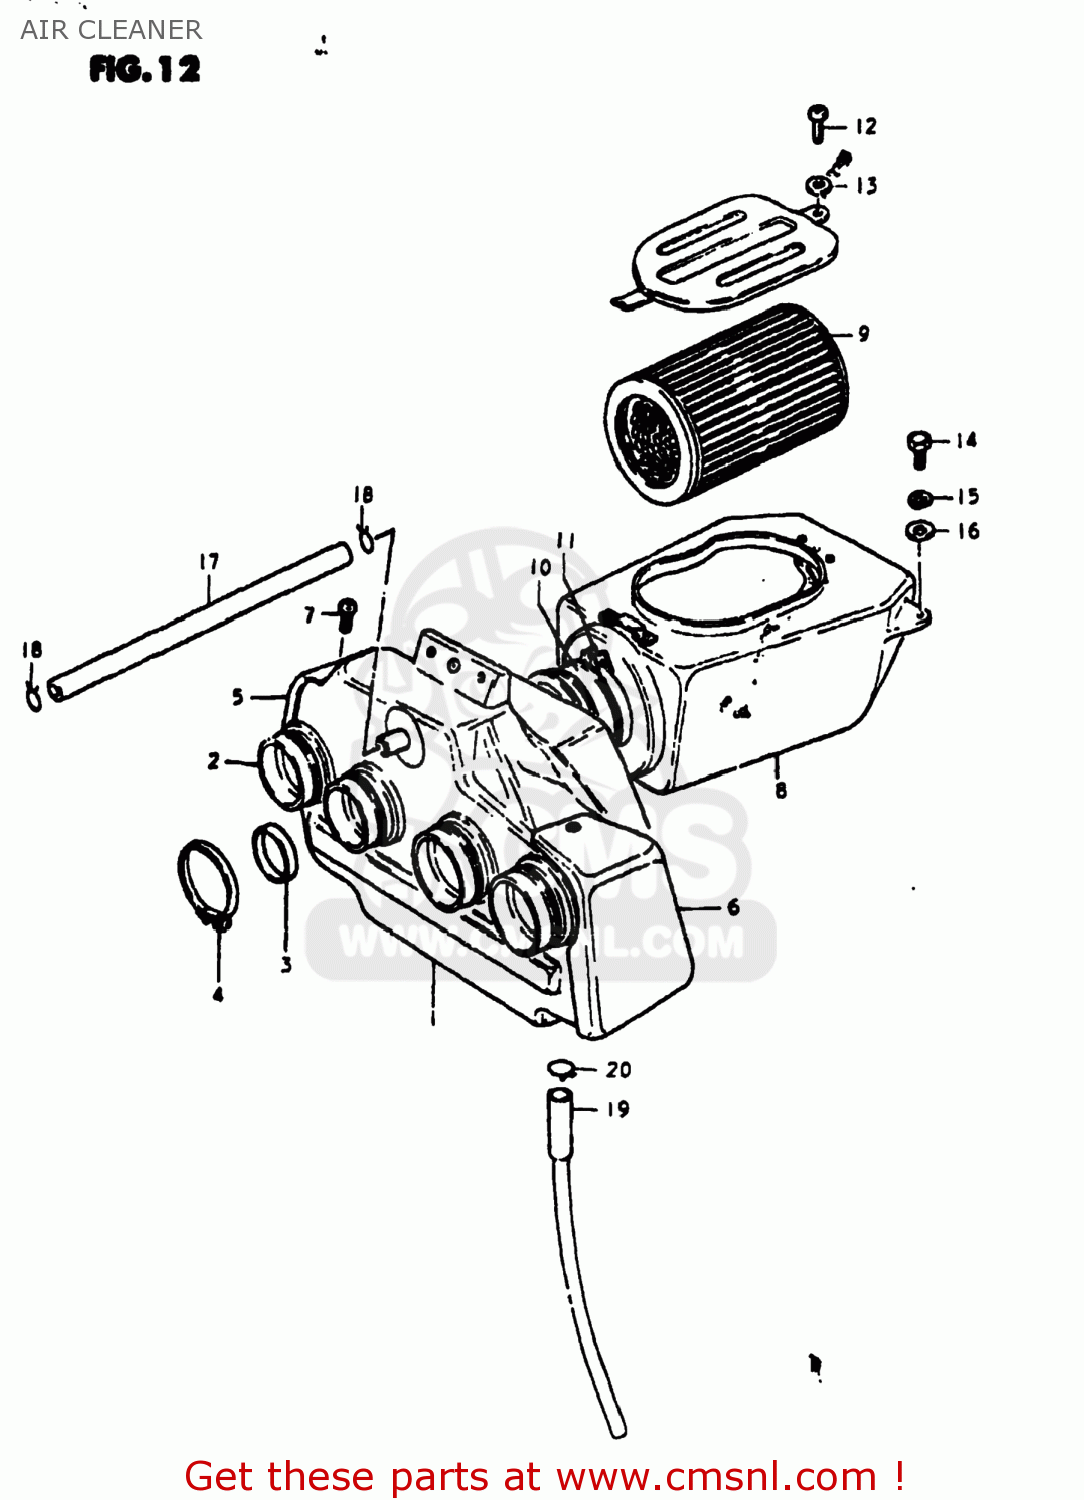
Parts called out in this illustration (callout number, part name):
1	CASE,AIR CLEANER,FRONT
2	TUBE,AIR CLEANER OUTLET
3	RING,CARBURETOR AIR IN
4	CLAMP
5	COVER,CASE,RIGHT
6	COVER,CASE,LEFT
7	SCREW
8	CASE ASSEMBLY,AIR CLEANER
9	FILTER,AIR CLEANER
10	HOSE,AIR CLEANER
11	BAND
12	SCREW
13	WASHER
14	BOLT, UPPER
15	LOCK WASHER
16	WASHER
17	TUBE,BREATHER
18	CLIP
19	DRAIN TUBE
20	CLIP
